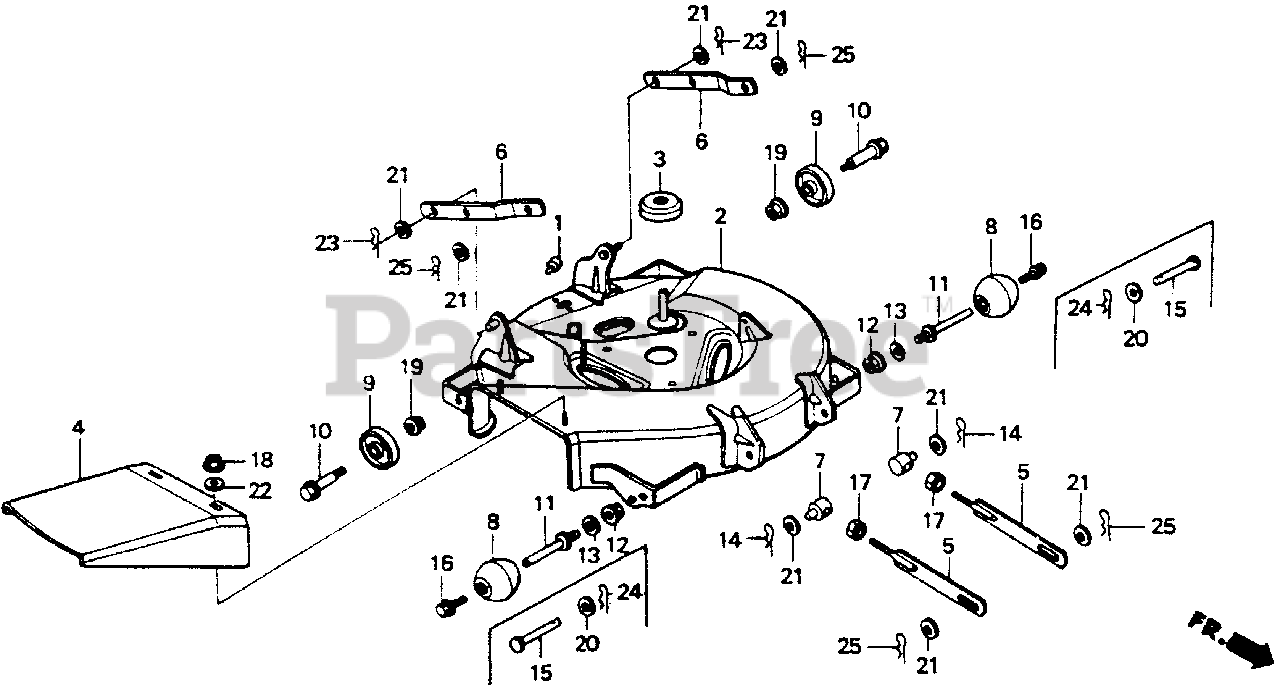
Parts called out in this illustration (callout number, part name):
1	RUBBER, STOPPER (NOT AVAILABLE)
2	HOUSING, CUTTER (NOT AVAILABLE)
3	CAP, TENSION ARM
4	ADAPTER, DISCHARGE
5	LINK, FR. DECK
6	LINK, RR. DECK
7	PIN, FR. LINK ADJUSTING
8	ROLLER, ANTI-SCALP
9	ROLLER, RR. ANTI-SCALP
10	BOLT, ANTI-SCALP ROLLER
13	WASHER, SPECIAL (12MM) (NOT AVAILABLE)
14	PIN, LOCK (2.3MM)
15	PIN, ANTI-SCALP ROLLER
17	NUT, HEX. (12MM)
18	NUT, FLANGE (8MM)
19	NUT, FLANGE (10MM)
20	WASHER, PLAIN (12MM)
21	WASHER, PLAIN (14MM)
22	WASHER, PLAIN (8MM) (NOT AVAILABLE)
22	WASHER, PLAIN (8MM)
23	PIN, COTTER (4X25)
24	PIN, LOCK (12MM)
25	PIN, LOCK (14MM)
